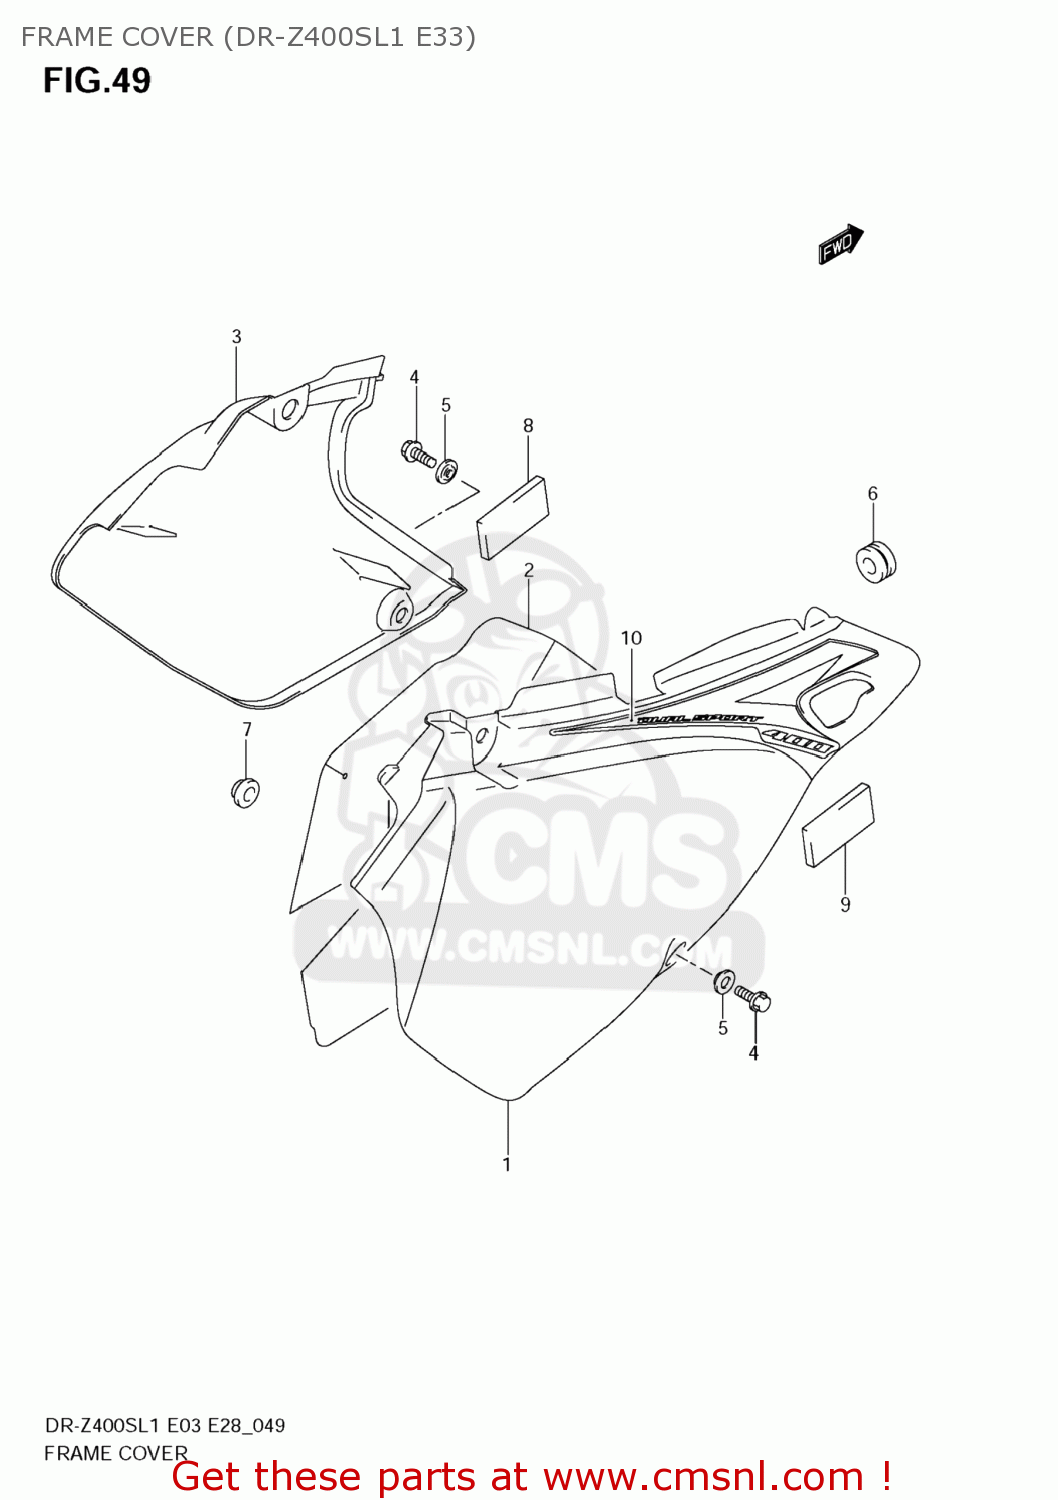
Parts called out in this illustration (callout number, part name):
1	COVER,FRAME,R(BLACK)
2	SHIELD,FRAME COVER,R
3	COVER,FRAME,L(BLACK)
4	BOLT(6X12)
5	WASHER
6	CUSHION
7	CUSHION
8	CUSHION,FRAME COVER,L
9	CUSHION
10	TAPE,FRAME COVER,R
